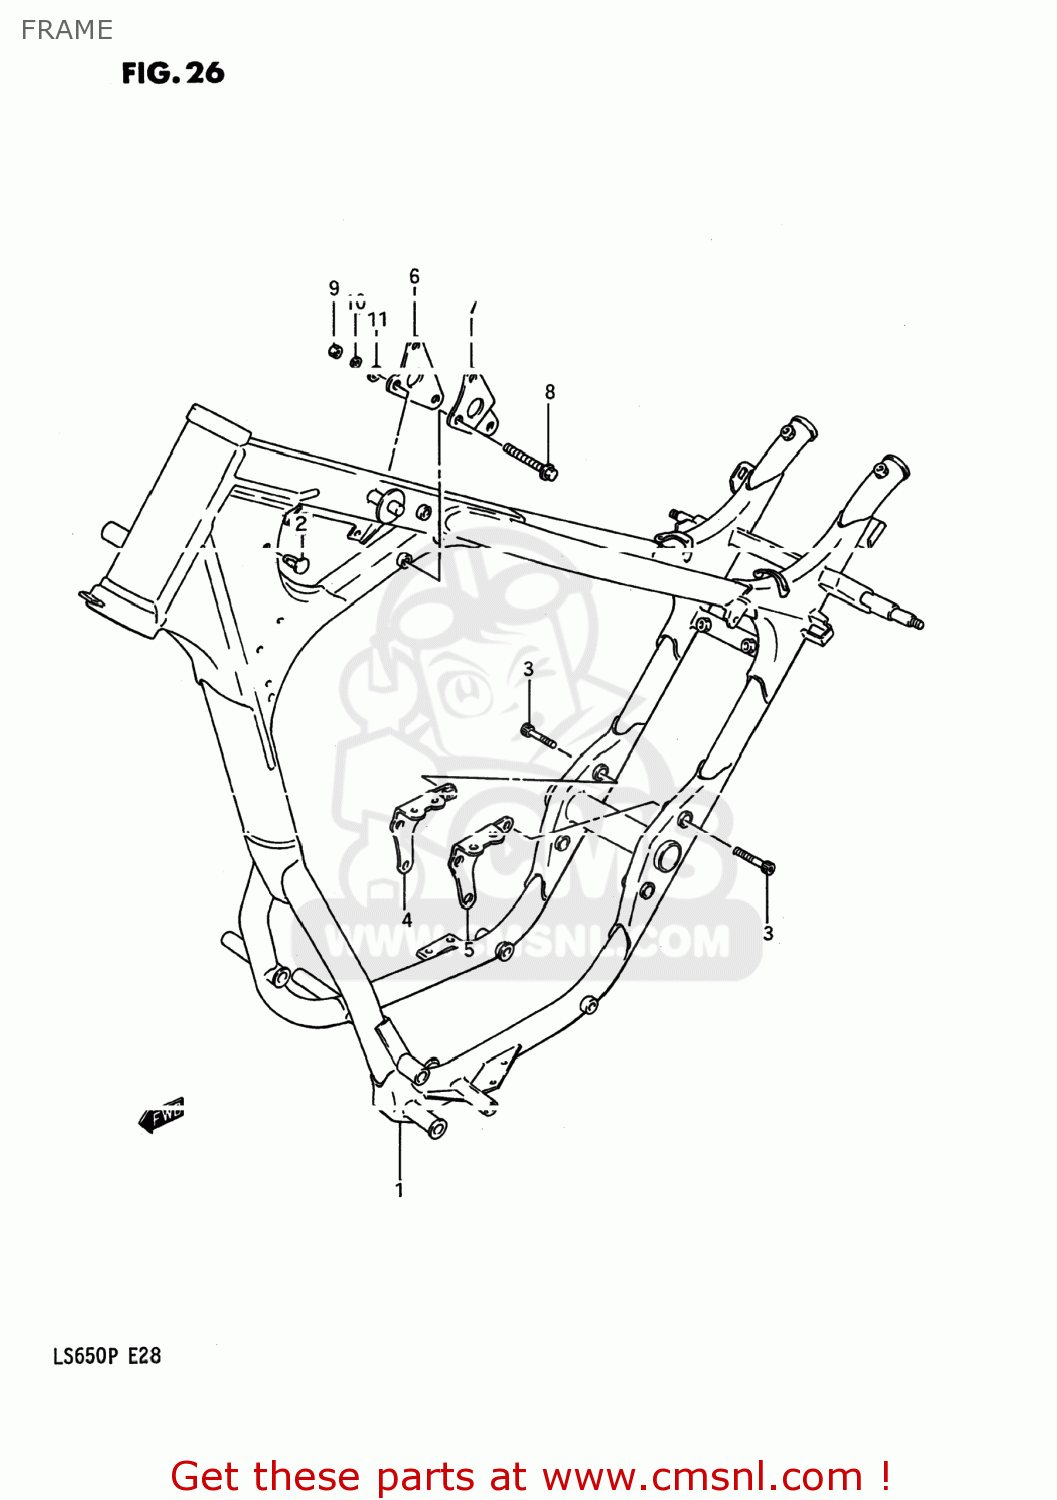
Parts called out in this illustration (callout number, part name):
1	FRAME
2	CLIP
3	BOLT(8X40)
4	PLATE,ENGINE MOUNT NO.4,R
5	PLATE,ENGINE MOUNT NO.4,L
6	PLATE,ENGINE MOUNT NO.5,R
7	PLATE,ENGINE MOUNT NO.5,L
8	BOLT(8X67)
9	NUT,T/F SHIFT LEVER
10	WASHER,LOCK,8.
11	WASHER 8MM
